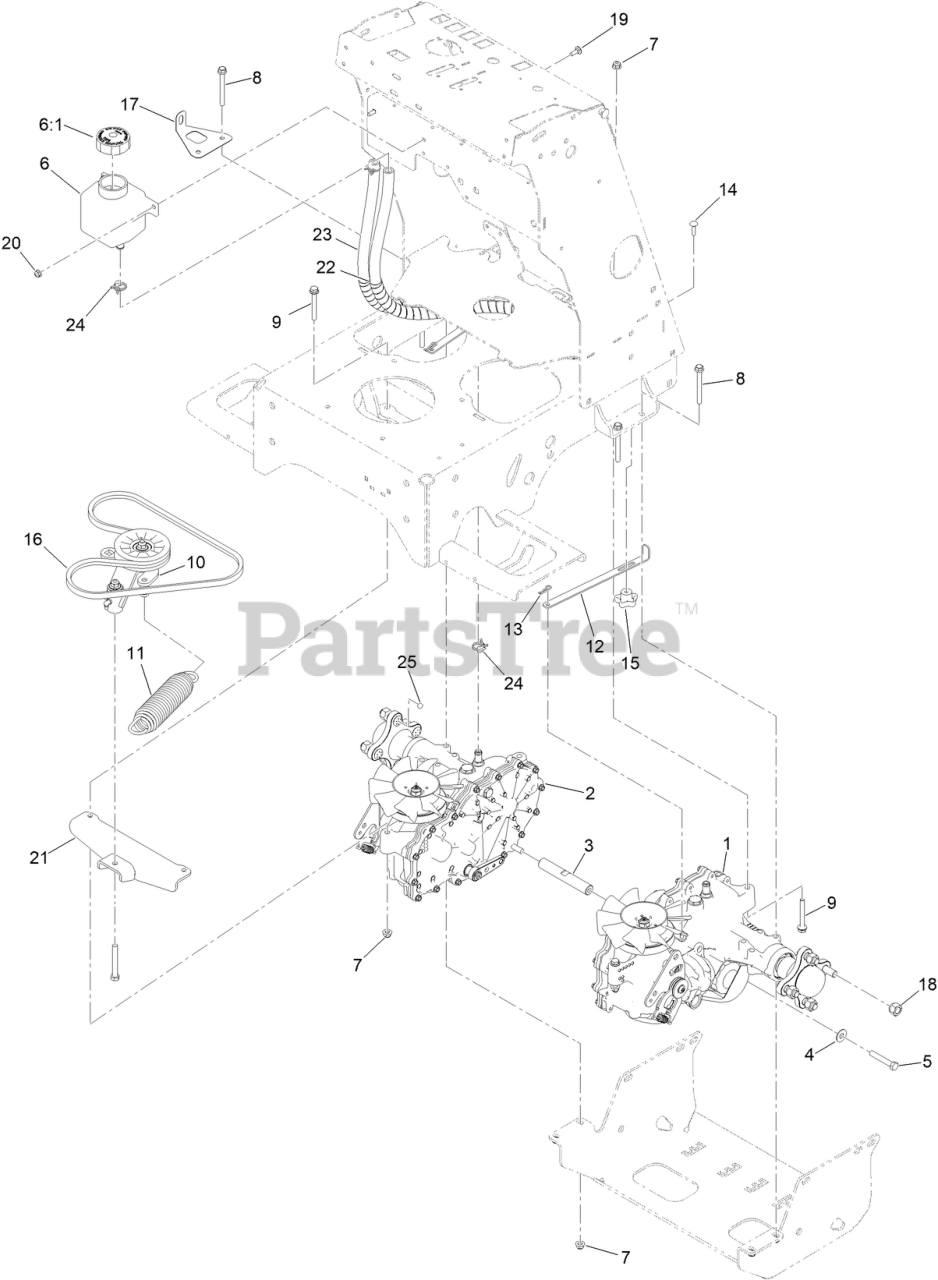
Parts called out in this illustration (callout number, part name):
1	ZT3400-LEFT
2	ZT3400-RIGHT
3	SHAFT-SPACER
4	WASHER-FLAT
5	HHCS,3/8-16X2-1/4ST/ST 18-8
6	TANK-HYD
6:1	CAP-RESERVOIR, HYD
7	NUT-HF, NI
8	SCREW-HHF
9	Screw-HHF
10	ASM-ARM, IDLER
11	SPRING-EXTENSION
12	ARM-HYDRO, BYPASS
13	PIN-COTTER
14	SCREW-CARR
15	KNOB-HANDLE
17	BRACKET-SENSOR, SPEED
18	NUT-LUG
19	BOLT,CARRIAGE,1/4-20X3/4,ST/ST
20	Nut-Hex Flange
21	MOUNT-IDLER
22	HOSE-EXPANSION
23	HOSE-EXPANSION
24	CLAMP-HOSE
25	MAGNET, SPEEDOMETER
